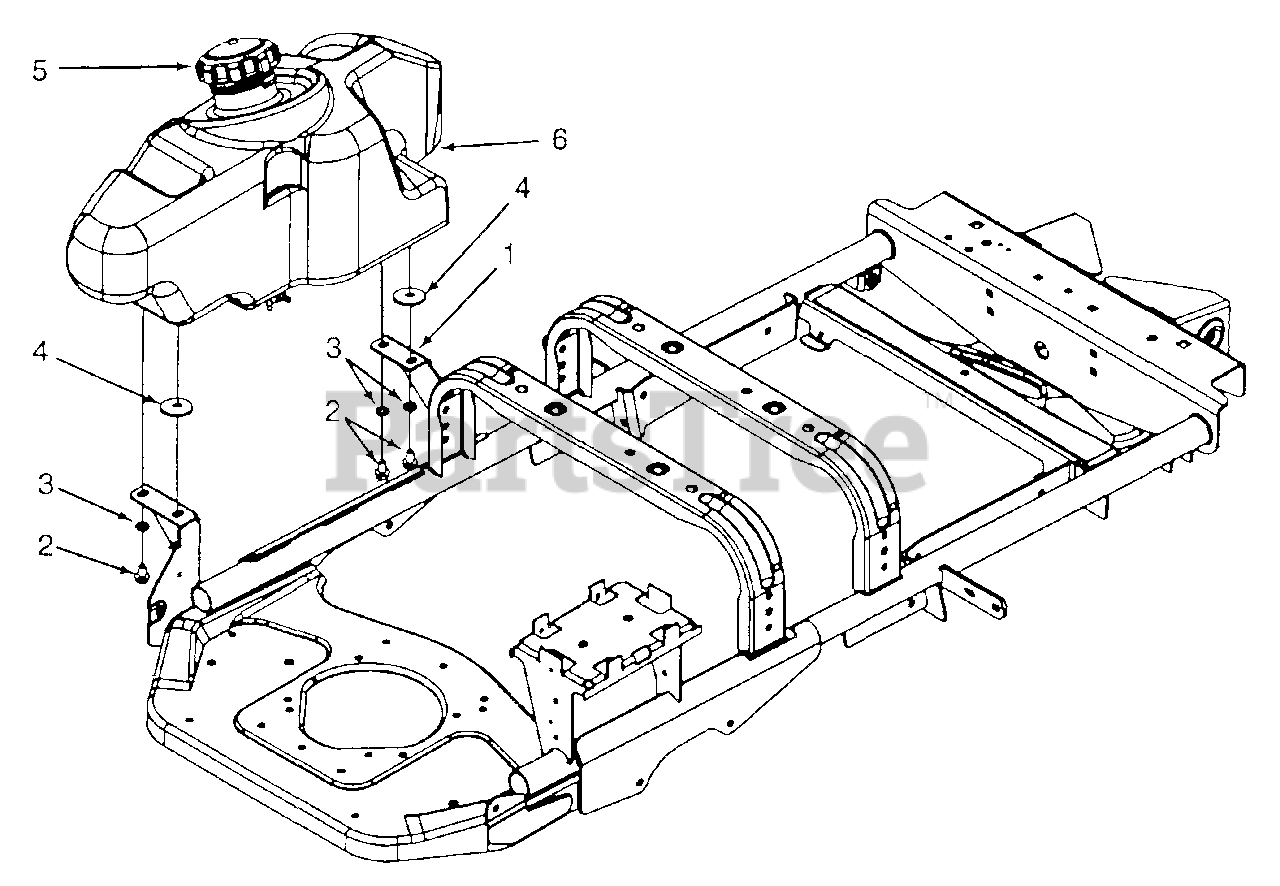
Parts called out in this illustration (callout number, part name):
3	Washer, Lock, 3/8
4	Washer, Flat, .390 x 1.5 x .10
5	Cap, Fuel
6	Fuel Tank
